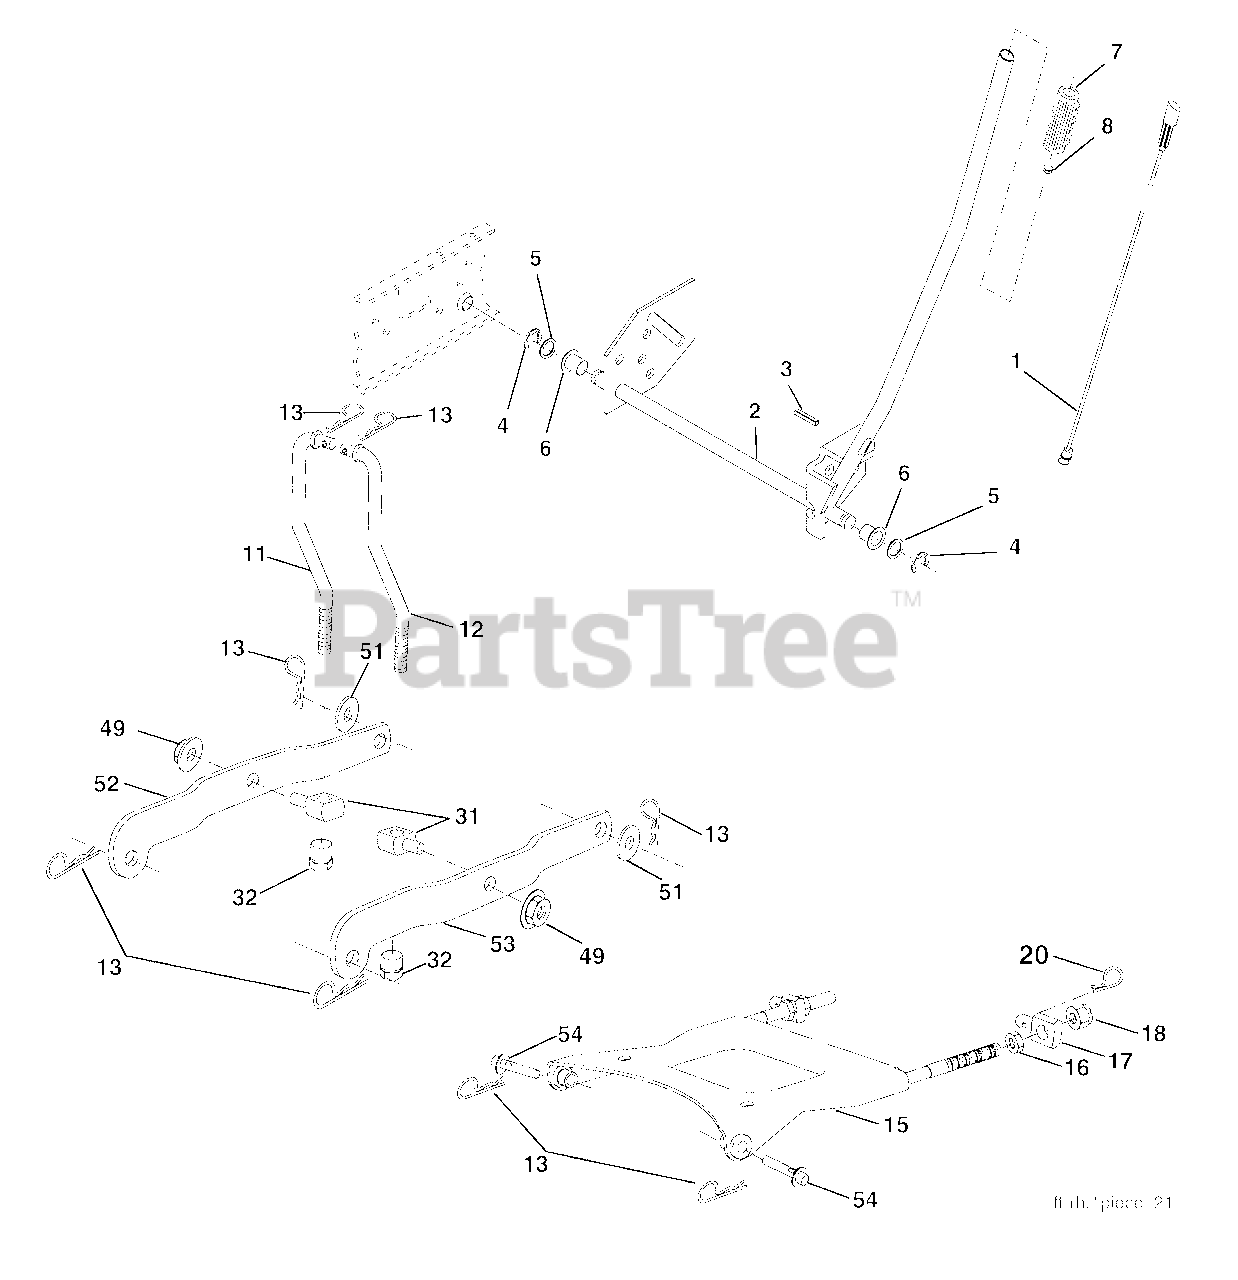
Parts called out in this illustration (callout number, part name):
1	Wire Asm Inner W/plunger 17 32
2	Shaft Asm Lift LH Inf Hgt P/L
3	Pin Groove 1 500 Zinc
4	E Ring #5133-62
5	Washer 21/32 x 1 x 21 Ga.
6	Bearing Nylon Blk 629 Id
7	Grip Handle
8	Button Plunger
11	Link Lift LH
12	Link Lift RH
13	Retainer Spring
15	Plate Asm Suspension Front
16	Nut Jam Hex 1/2-13 unc
17	Trunnion Blk Zinc
18	Nut Lock W/wsh 1/2-13 unc
20	Retainer Spring
31	Trunnion Suspension Arm
32	Nut Lift Link 7/16-20
49	Nut Hex Flange Lock
51	Washer 17/32 x 7/8 x 16 Ga.
52	Arm Suspension Rear LH
53	Arm Suspension Rear RH
54	Pin Flange
